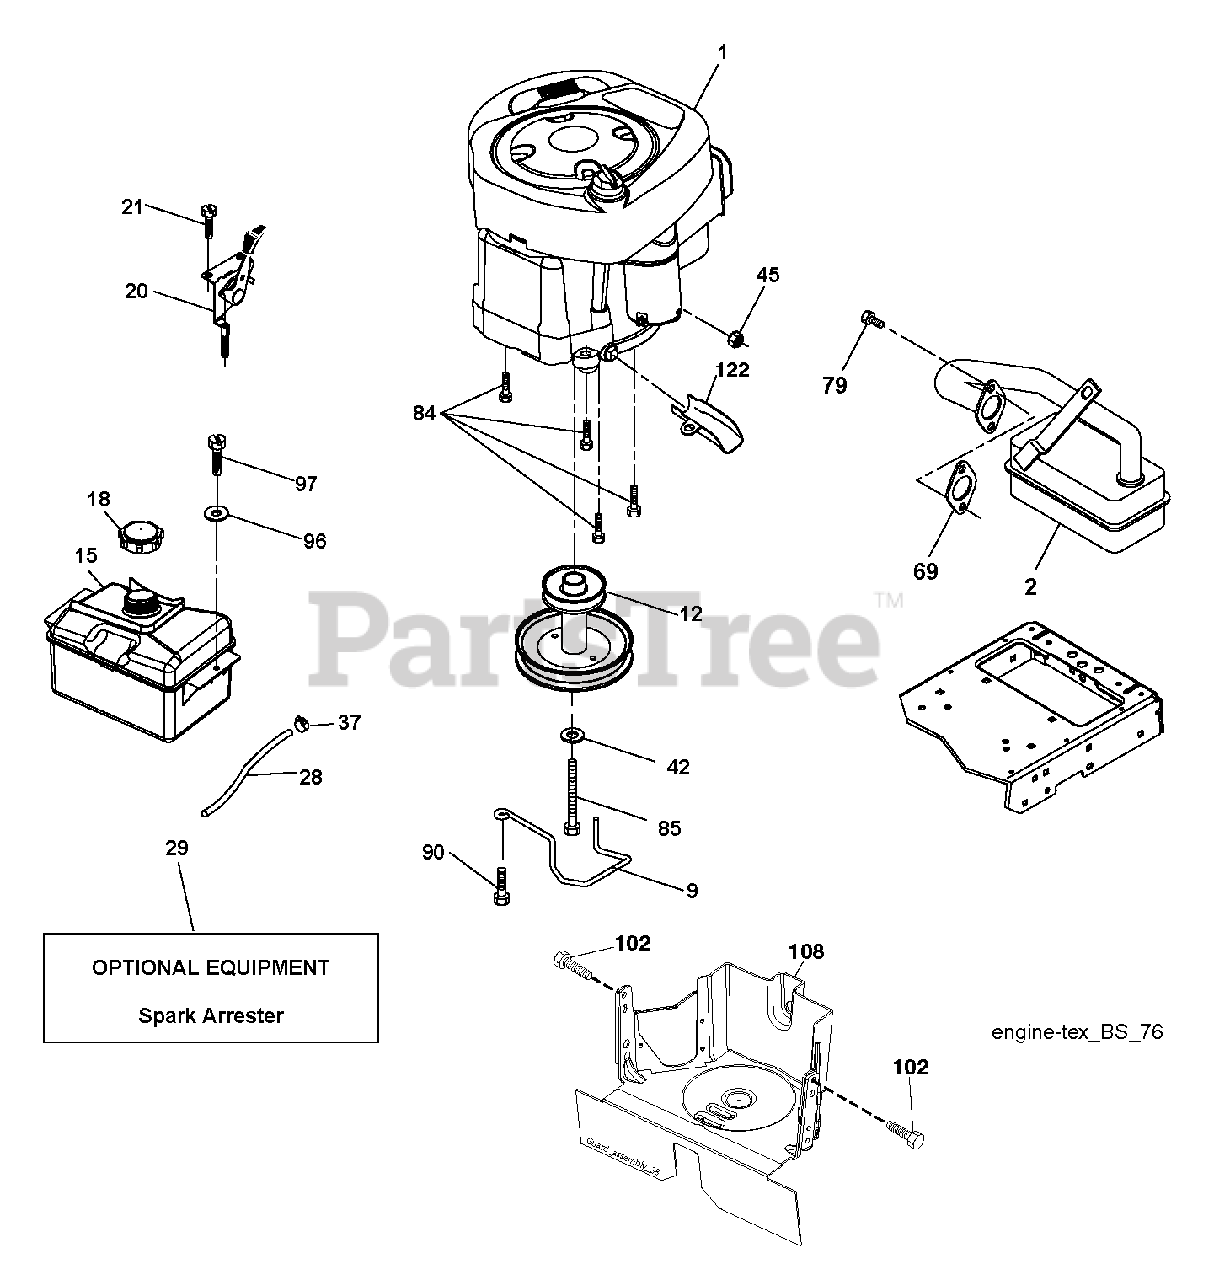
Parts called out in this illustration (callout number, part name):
2	MUFFLER.B&S.MODEL.21.11HP.OHV
9	KEEPER.BELT.ENGINE.3.25 (3 2)
12	PULLEY.ENG.CL.MECH.SLVR.LT/YT
15	FUEL.TANK.ASM.NON-EPA
18	CAP ASM.FUEL.2.25"FR.
20	CONTROL.TH/CK.C.
21	SCREW.#10 X 0.750.BOS
28	LINE.FUEL.20
29	KIT.SPARK ARRESTOR 794945 B&S
37	HOSE CLAMP
42	LOCKWASHER
45	NUT
69	REPL BY 532 27 22-93
79	SCREW.SOCKET HD.5/16-1
84	SCREW.3/8-16
85	BOLT HEX 7/16-20X4-1/4"
90	SCREW 3/8-16X1
97	SCREW HEXWSHR 1/4-20X3/4
102	SCREW
108	COVER PULLEY
122	EXTENSION DRAIN OIL
